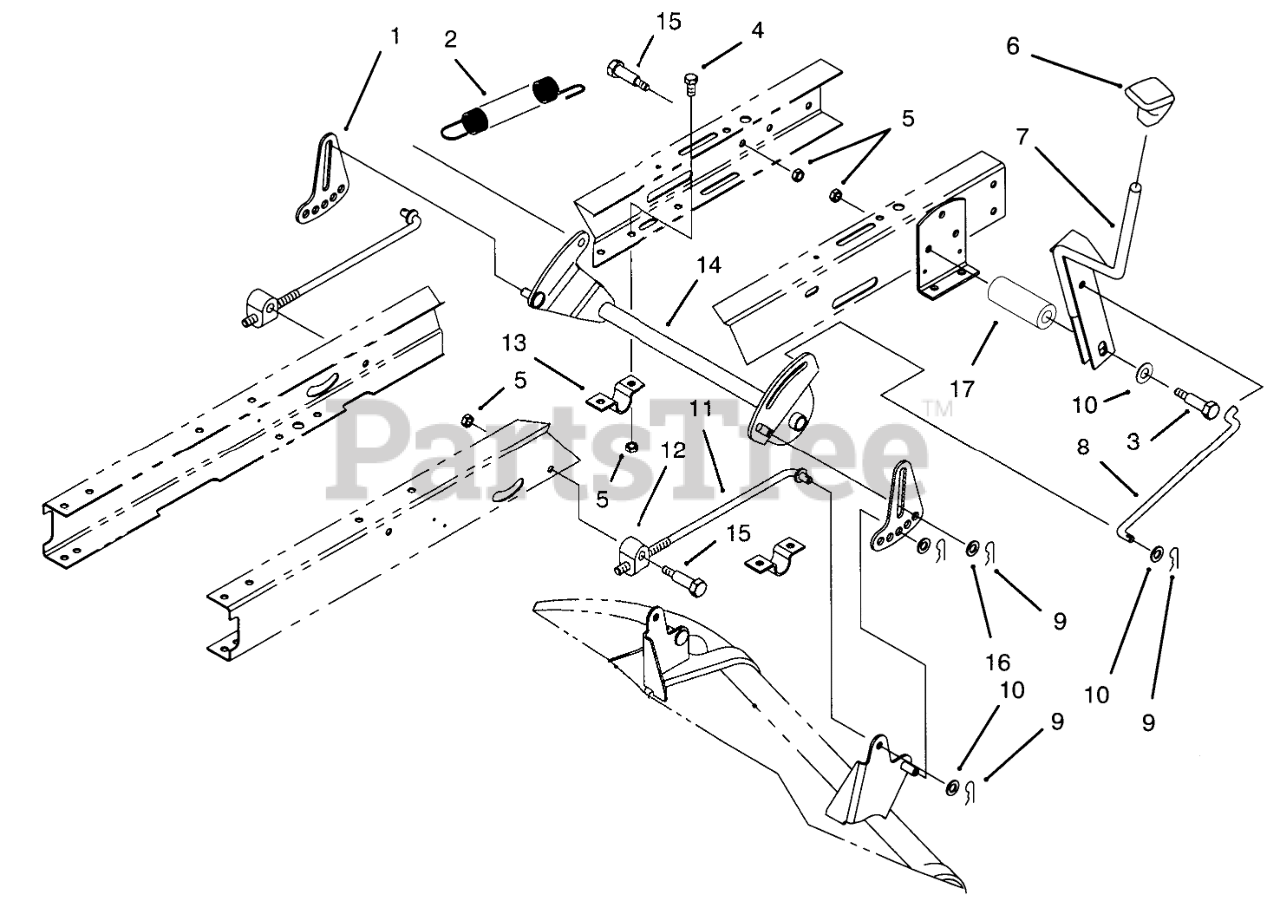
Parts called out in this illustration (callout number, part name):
1	Link-Adjusting H.O.C
2	SPRING-EXTENSION
3	SCREW-HH
4	SCREW-HH
5	NUT-LOCK, NI
6	SHIFT KNOB
7	Lever-H.O.C.
8	LINK-HOC
9	PIN-COTTER
10	WASHER-FLAT
11	ROD-HANGER, REAR
12	TRUNNION-HOC
13	CLAMP-PIVOT, HOC
14	Pivot-H.O.C.
15	SCREW-SHOULDER, HH
16	WASHER-HARDENED
17	SPACER
